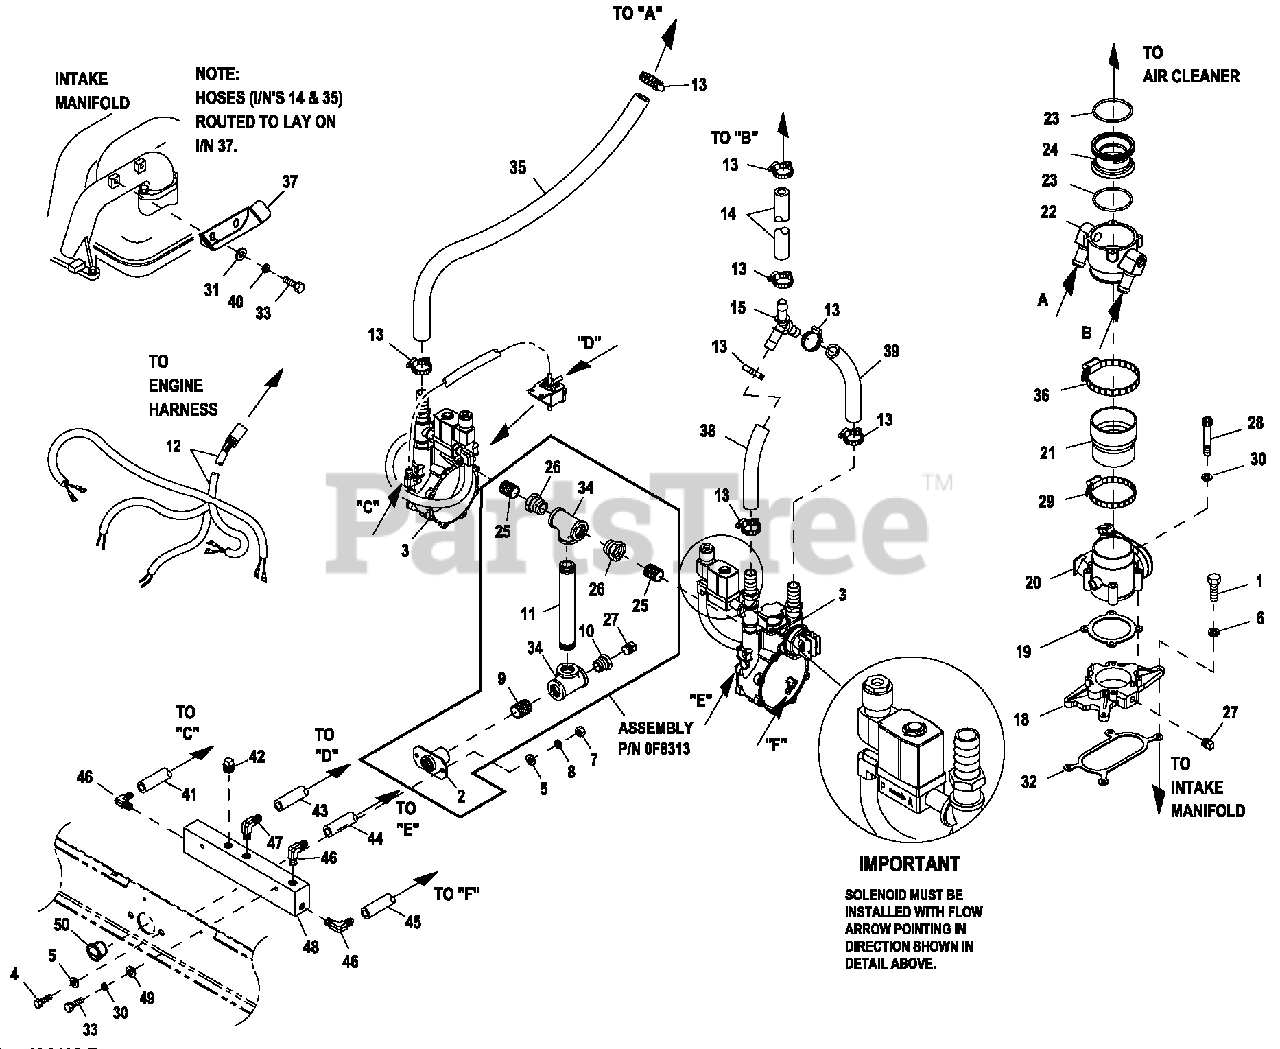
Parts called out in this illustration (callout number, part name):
1	SCREW HHC 5/16-18 X 1-1/4 G5
2	SUPPORT NAT GAS SOLENOID
3	REG 6.8L CPL 100 KW N/G EMISS
4	SCREW HHC M12-1.75 X 30 C8.8
5	WASHER FLAT 1/2 ZINC
6	WASHER LOCK M8-5/16
7	NUT HEX M12-1.75 G8 YEL CHR
8	WASHER LOCK 1/2
9	NIPPLE CLOSE 1.25 NPT X 1.625
10	BSHG RDCR HEX 1-1/4 X 1/4FNPT
11	NIPPLE PIPE 1-1/4 NPT X 3
12	HARNESS FUEL JUMPER DUAL REG
13	CLAMP HOSE #8 .53-1.00
14	HOSE 3/4 ID SAE-30R2 (42" LG)
15	Y CONNECTOR 500 SERIES BARBS
18	ADAPTOR THROTTLE BODY
19	GAS KET GOVERNOR ACTUATOR
20	ACTUATOR BOSCH 60 GOVERNOR
21	REDUCER 3.0" TO 2.75" TURBO
22	MIXER 40/60MM ACTUATOR ASSY
23	O-RING 2-3/4 X 3/32 X 2-15/16
24	VENTURI, THROTTLE 42MM
25	NIPPLE CLOSE 3/4 X 1.375
26	BSHG RDCR HEX 1-1/4-3/4
27	PLUG STD PIPE 1/4 STEEL SQ HD
28	SCREW SHC M6-1.0 X 50 C8.8
29	CLAMP HOSE #44 2.31-3.25
30	WASHER LOC K M6-1/4
31	WASHER FLAT M6
32	GAS KET ADAPTER THROT BODY
33	SCREW HHC M6-1.0 X 20 G8.8
34	PIPE TEE 1-1/4 NPT
35	HOSE 3/4 ID SAE-30R2 (45" LG)
36	CLAMP HOSE #52 2.81-3.75
37	BRACKET, HOSE RISER
38	HOSE 3/4 ID SAE-30R2 (9.5" LG)
39	HOSE 3/4 ID SAE-30R2 (12" LG)
40	WASHER LOC K M6-1/4
41	HOSE VACUUM 5/32 (5"LG)
42	PLUG STD PIPE 1/8 STEEL SQ HD
43	HOSE VACUUM 5/32 (18"LG)
44	HOSE VACUUM 5/32 (6"LG)
45	HOSE VACUUM 5/32 (8"LG)
46	BARBED EL 90 3/16X1/8
47	BARBED EL W/VENT (.052")
48	MANIFOLD, EMISSIONS VACUUM
49	WASHER FLAT 1/4-M6 ZINC
50	PLUG PLASTIC 1.25" TAPERED CAP
